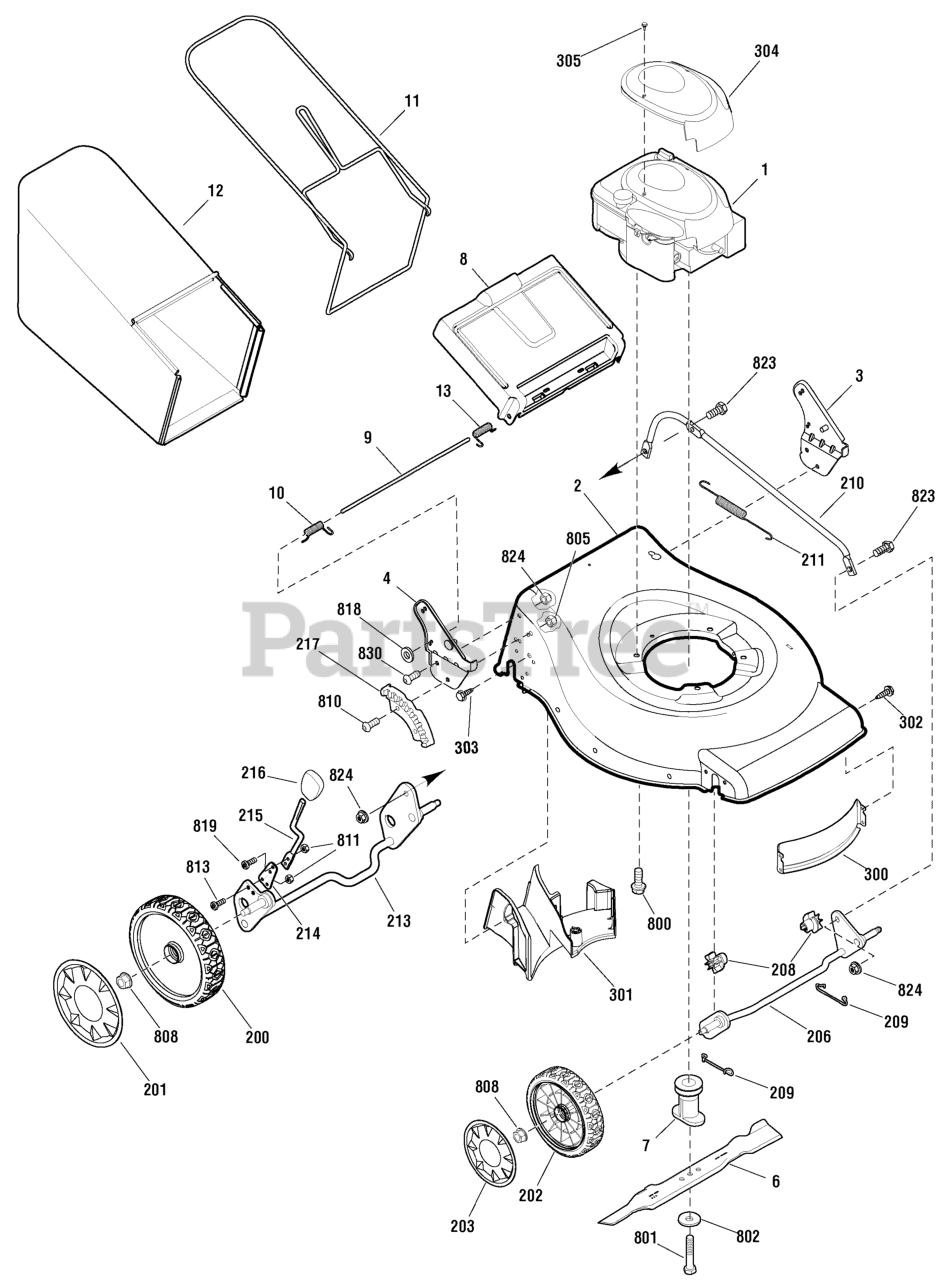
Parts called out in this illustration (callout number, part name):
1	* ENGINE, 5.5GT Briggs & Stratton
2	MOWER HOUSING
3	BRACKET ASSEMBLY, Left Handle
4	BRACKET ASSEMBLY, Right Handle
6	BLADE, 16 Inch
7	BLADE ADAPTER ASSEMBLY
8	DOOR, Rear
9	ROD, Rear Door
10	SPRING, Torsion Rear Door, Right
11	FRAME ASSEMBLY
12	BAG ASSEMBLY
13	SPRING, Torsion Rear Door, Left
200	WHEEL, Rear
201	HUBCAP, Rear
202	WHEEL, Front
203	HUBCAP, Front
206	CROSSBAR ASSEMBLY, Front
208	BUSHING, Front Crossbar
209	SPRING, Clip Crossbar
210	LINK, Single Lever
211	SPRING, Extension
213	REAR CROSSBAR
214	SPRING, Adjuster
215	LEVER, Height Adjustment
216	KNOB, Adjuster
217	BRACKET, Height Adjuster
300	BAFFLE, Front, 38cm
301	BAFFLE, Rear, 38cm
302	SCREW, Pan Head, Taptite, 1/4-20 x 1/2
303	SCREW, Pan Head, Taptite, 1/4-15 x 5/8
304	SHROUD, With Label
305	CAPSCREW, Hex Washer Head
800	SCREW, Hex Washer Self-Tap, 3/8-16 x 1
801	BOLT, Blade, 3/8-24 x 2
802	WASHER, Belleville 7/16 ID
805	NUT, Nylock, M8 x 1-1/4
808	NUT, Flange Lock 3/8-16
810	BOLT, Hex Key Head, M8 X 1.25
811	NUT, Nylock
813	SCREW, Torx Head, M5 x .8 x 14mm
818	PUSHNUT, 1/4
819	SCREW, Torx Head, M5 x .8 x 12.5mm
823	BOLT, Shoulder, 5/16-18 x 1
824	NUT, Nylock, M8 x 1-1/4
830	SCREW, 5/16-18 x 1.1, Hex Washer
